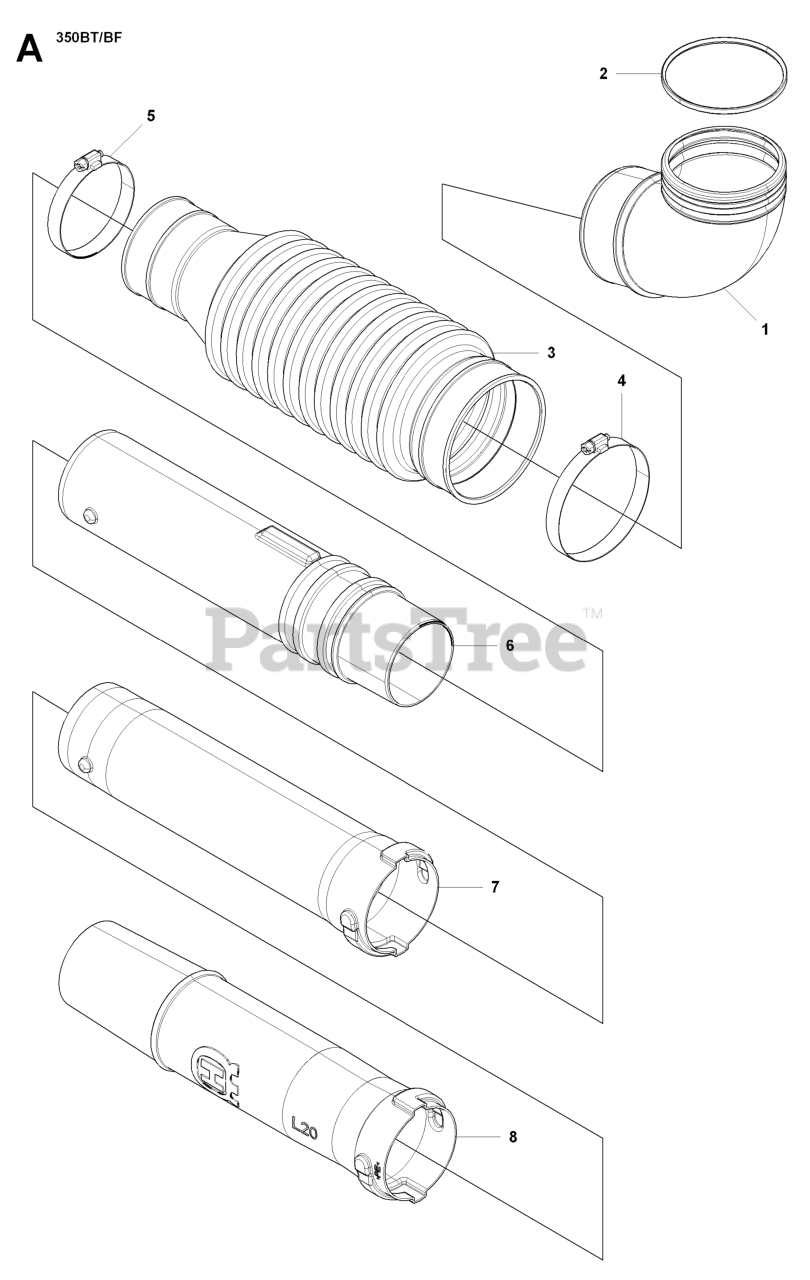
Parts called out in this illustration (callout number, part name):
3	PIPE FLEX T403051110
4	CLAMP(F115)
6	TUBE SWIVEL JOINT
7	TUBE MIDDLE Z681151211
